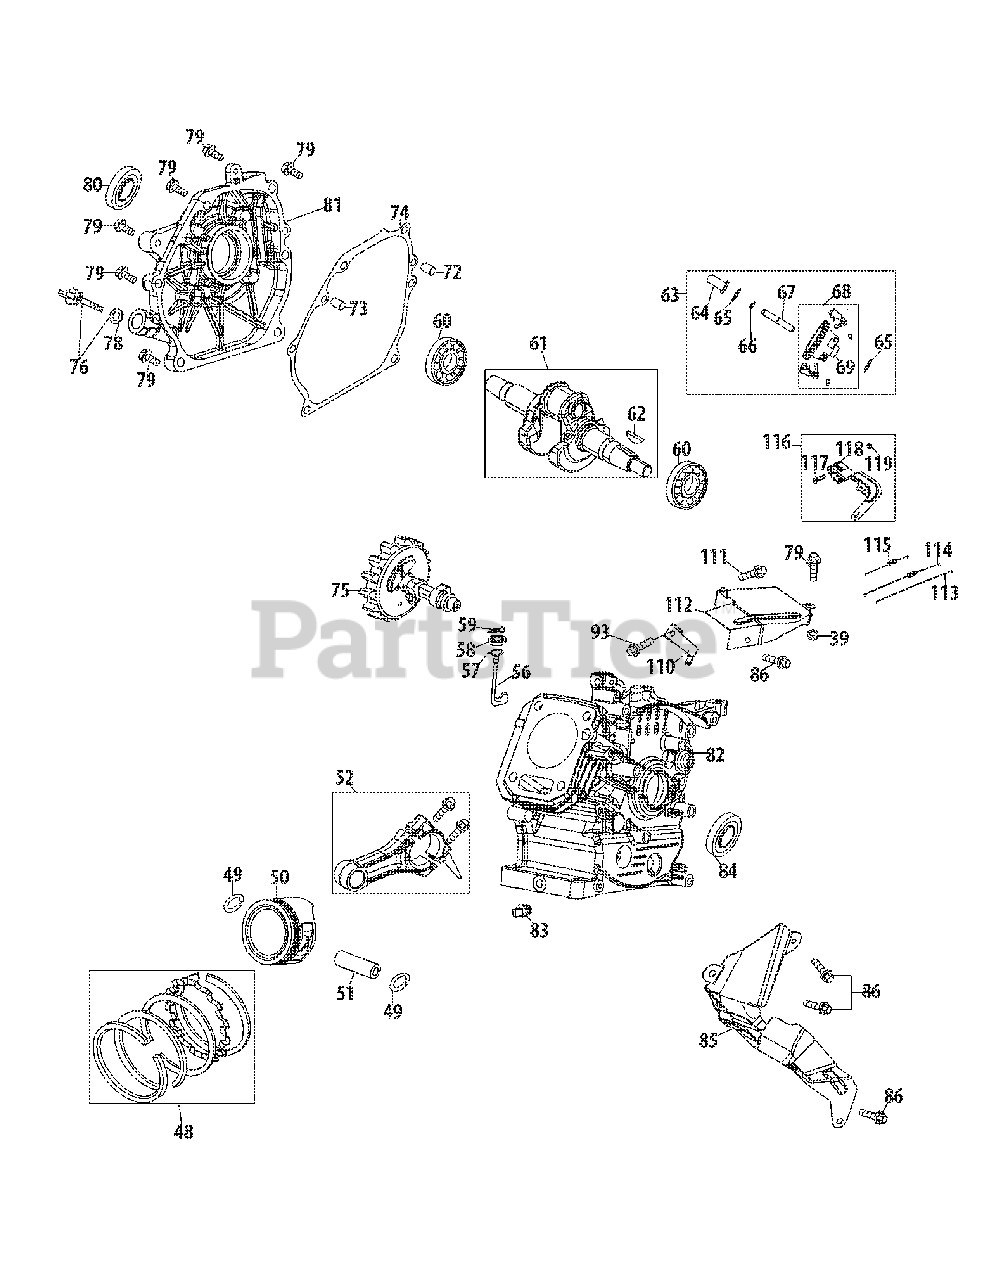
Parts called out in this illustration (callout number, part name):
39	Flange Nut M6
48	Piston Ring Set
49	Piston Pin Snap Ring
51	Piston Pin
52	Connecting Rod
56	Shaft,Governor Arm
57	O-Ring 5.2×1.9
58	Oil Seal 6×11×4
59	Cotter Pin
61	Crankshaft
62	Woodruff Key
63	Governor Gear
64	Governor Cup
65	Washer 6.2×0.6×15
66	Retaining Rings, Governor Shaft
67	Governor Shaft
68	Governor B0Dy
69	Governor Gear
72	Dowel Pin 9×14
73	Dowel Pin 7×14
74	Gasket, Crankcase Cover
78	O-Ring 15.8×2.5
79	Bolt M6×28
80	Oil Seal 25×41.25×6
81	Crankcase Cover
82	Crankcase
83	Drain Bolt Npt 1/8
84	Oil Seal 22×35×7
85	Shroud
86	Bolt M6×10
93	Bolt M6×12
110	Governor Spring Bracket
111	Bolt M8×14
112	Governor Shield
113	Throttle Linkage
114	Idle Spring
115	Governor Return Spring
116	Governor Lever
117	Bolt M6×21
118	Governor Lever
119	Flange Nut M6
